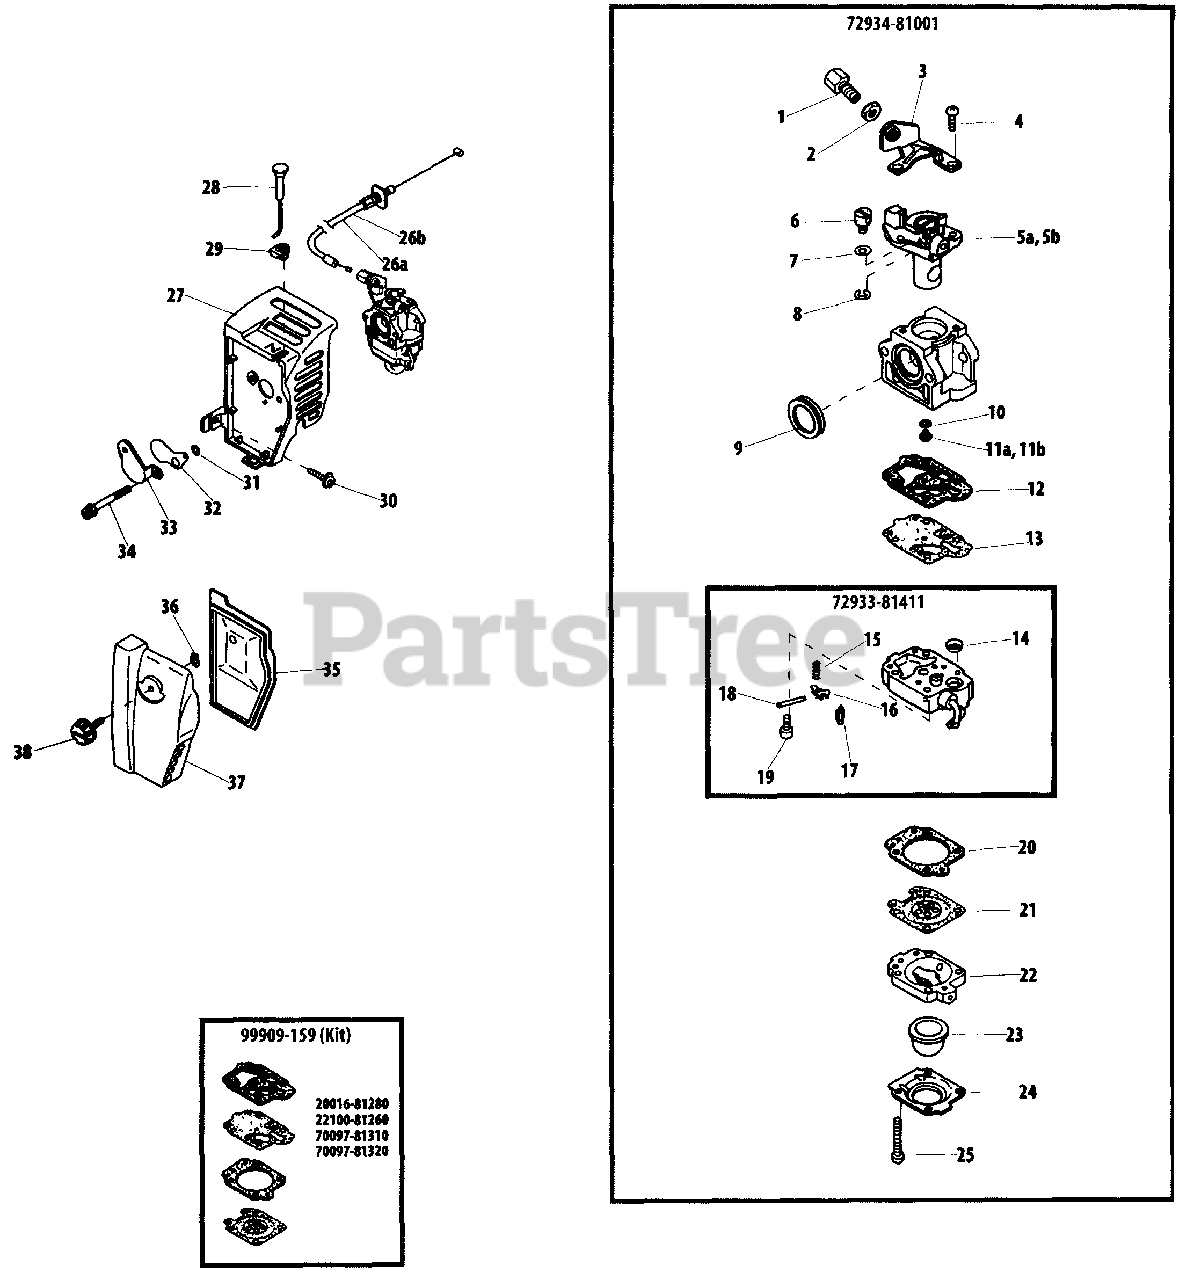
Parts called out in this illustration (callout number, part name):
1	NUT, CABLE ADJUST
2	NUT
3	BRACKET, CABLE
4	SCREW
5A	THROTTLE VALVE ASSY
5B	THROTTLE VALVE ASSY
6	SWIVEL
7	WASHER
8	RING, RETAINING
9	SEAL
10	O-RING
11A	JET
11B	JET, MAIN - 37
12	GASKET, PUMP
13	DIAPHRAGM, PUMP
14	STRAINER
15	SPRING, METERING LEVER
16	LEVER, METERING
17	VALVE, INLET NEEDLE
18	PIN, METERING LEVER
19	SCREW, METERING LEVER PIN
20	GASKET, METERING
21	DIAPHRAGM, METERING
22	BASE, PURGE
23	BULB, PURGE
24	RETAINER, PURGE BULB
25	SCREW, PUMP COVER
26A	CABLE, THROTTLE
26B	CABLE, THROTTLE
27	CASE, AIR FILTER
27	CASE, AIR CLEANER (NON EPA)
28	ROD, CHOKE
29	GROMMET
30	SCREW
31	WASHER
32	PLATE, CHOKE
33	PLATE, PREVENT
34	SCREW - 5X45
35	FILTER, AIR
36	RING, RETAINING
37	COVER, AIR FILTER
38	SCREW
